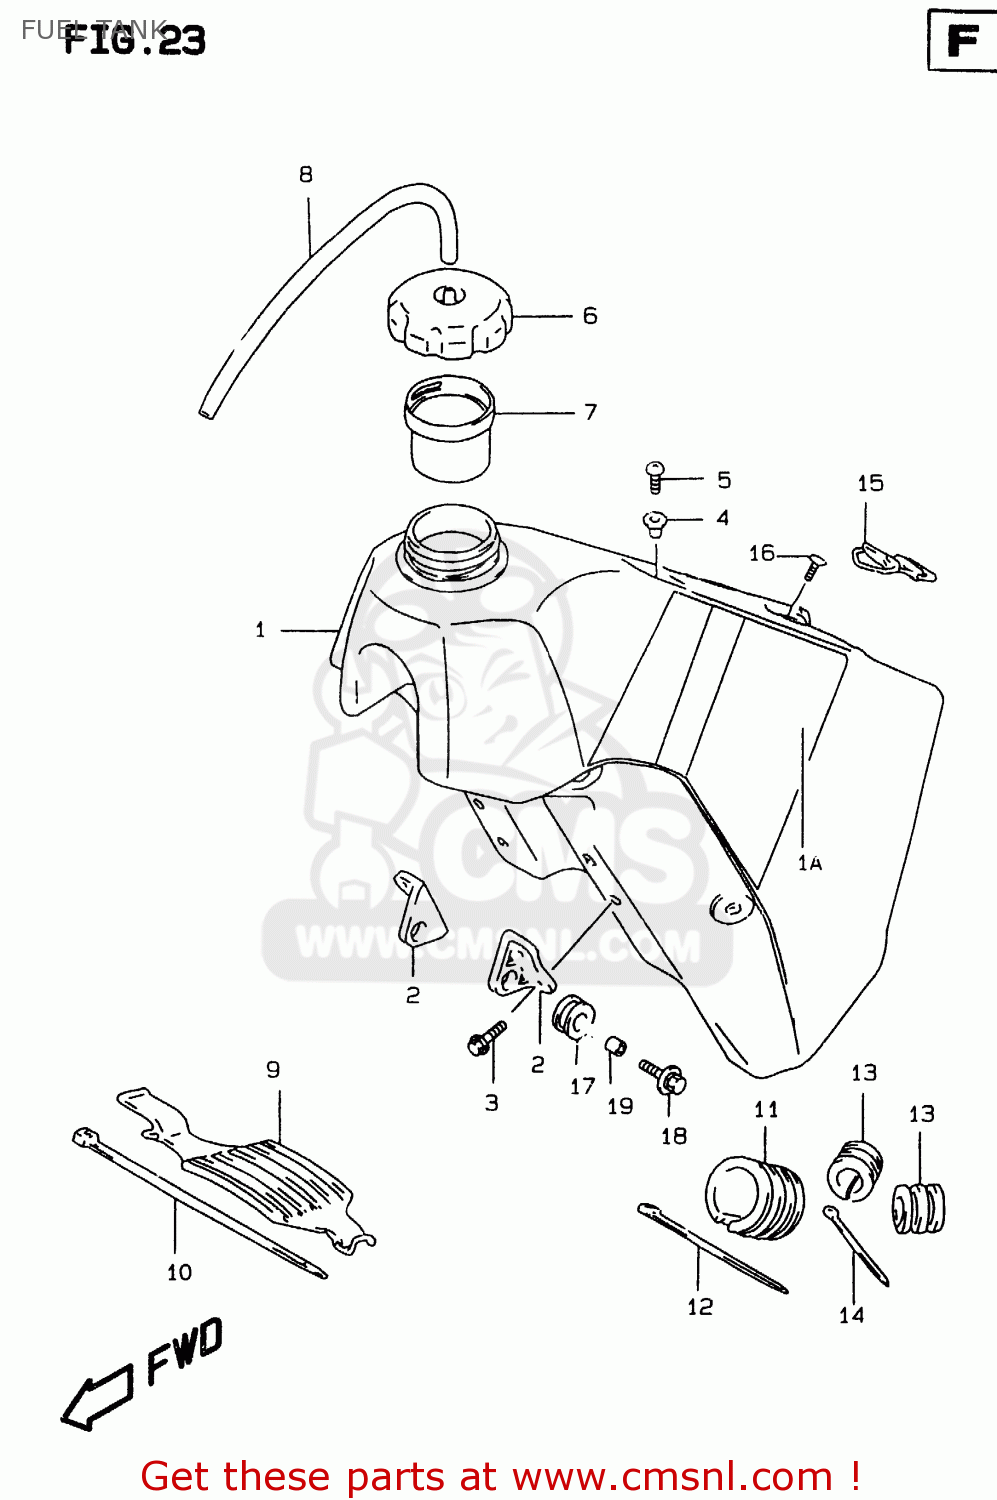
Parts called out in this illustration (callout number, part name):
1	TANK, FUEL (YELLOW)
1A	TAPE SET,FUEL TANK
2	BRACKET,FUEL TANK FR
3	BOLT
4	HOOK,SEAT FR
5	SCREW
6	CAP ASSY,FUEL TANK
7	TUBE,FILLER INLET
8	HOSE(5X8.2X600)
9	CUSHION,FUEL TANK NO.1
10	CLAMP(L:250)
11	CUSHION,FUEL TANK NO.2
12	CLAMP(L:300)
13	CUSHION,FUEL TANK NO.1
14	CLAMP(L:145)
15	BAND,FUEL TANK RR
16	SCREW
17	CUSHION
18	BOLT(8X30)
19	SPACER(8.5X12X13.5)
